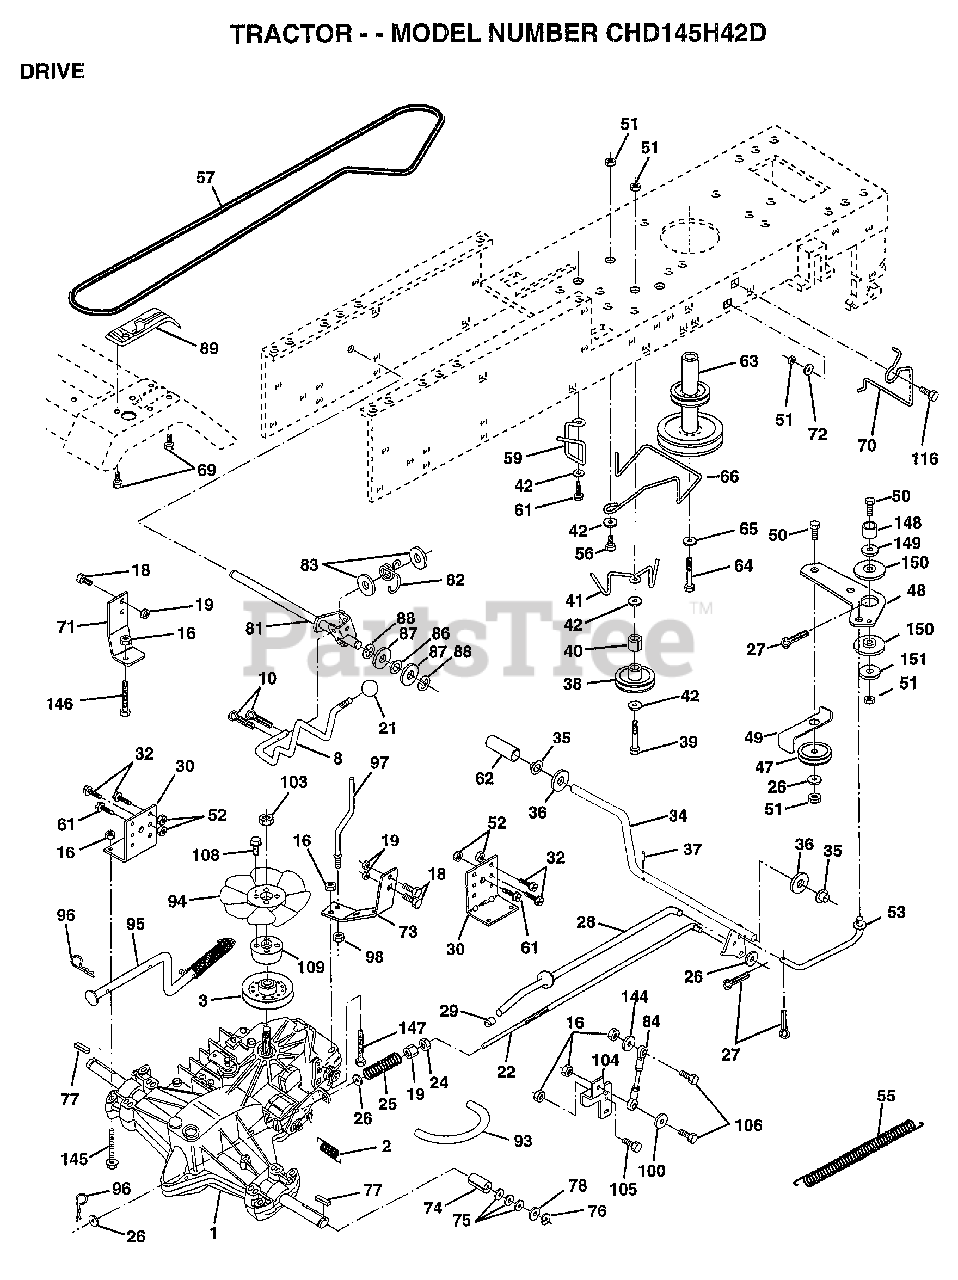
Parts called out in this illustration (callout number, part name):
1	TRANSAXLE HYD 0319-0500
2	SPRING RET BRAKE
3	PULLEY.4.20.HYDRO
8	ROD SHIFT FEND LT
10	PIN COTTER 1/8
16	NUT
18	BOLT
19	NUT
21	KNOB T (1/2-HOLE)
22	ROD.BRAKE.HYDRO.
24	NUT
25	SPRING ROD LT
26	WASHER
27	COTTER PIN
28	ROD.BRAKE.PARK.LT
29	PLUNGER CAP T
30	TRANSAXLE MTG BKT
32	BOLT
34	SHAFT ASM-PEDAL F
35	NYLON BEARING
36	WASHER LT
38	PULLEY.IDLER.FLAT
39	BOLT
40	SPACER T
42	WASHER
48	BELLCRANK.CLUTCH
49	RETAIN BELT
53	"LINK, CLUTCH T"
55	"SPRING, RETURN LT"
57	BUMPER.ASM.W/PY
59	KEEPER BELT CNTSP
61	SCREW
62	PEDAL COVER T
63	PULLEY.ENGINE
64	BOLT
65	LOCKWASHER
66	KEEPER-BELT
69	SCREW HEXWSH H-L
70	KEEPER BELT ENG
71	STRAP.TORQ.LH.HYD
72	WASHER
73	STRAP.TORQ.RH.HYD
74	SPACER SPLIT
75	WASHER
76	E-RING LT
77	SQUARE KEY
78	WASHER
81	SHAFT.CROS.500.HY
82	"SPRING,TORSION"
83	WASHER
84	ROD.TIE.BALL.HYD.
86	BUSHING
87	WASHER D
88	KLIP RING
93	"LINE FUEL HYD 4"""
94	"FAN 7"" HYDRO"
96	RETAINER M
97	KEEPER.BELT.RH.HY
98	NUT
100	WASHER M
104	ARM.CONTROL.PUMP
105	SCREW CAP 5/16-18
106	BOLT
108	SCREW.HXHD.10-20
109	ADAPTOR.FAN.HYDRO
116	BOLT RDHD 3/8-16
144	WASHER
145	BOLT.HEX.FLGHD
146	BOLT.HEX.FLGHD.
147	BOLT.HEX.FLGHD
149	SPACER RETAINER
150	BUSHING.NYLON
151	WASHER
